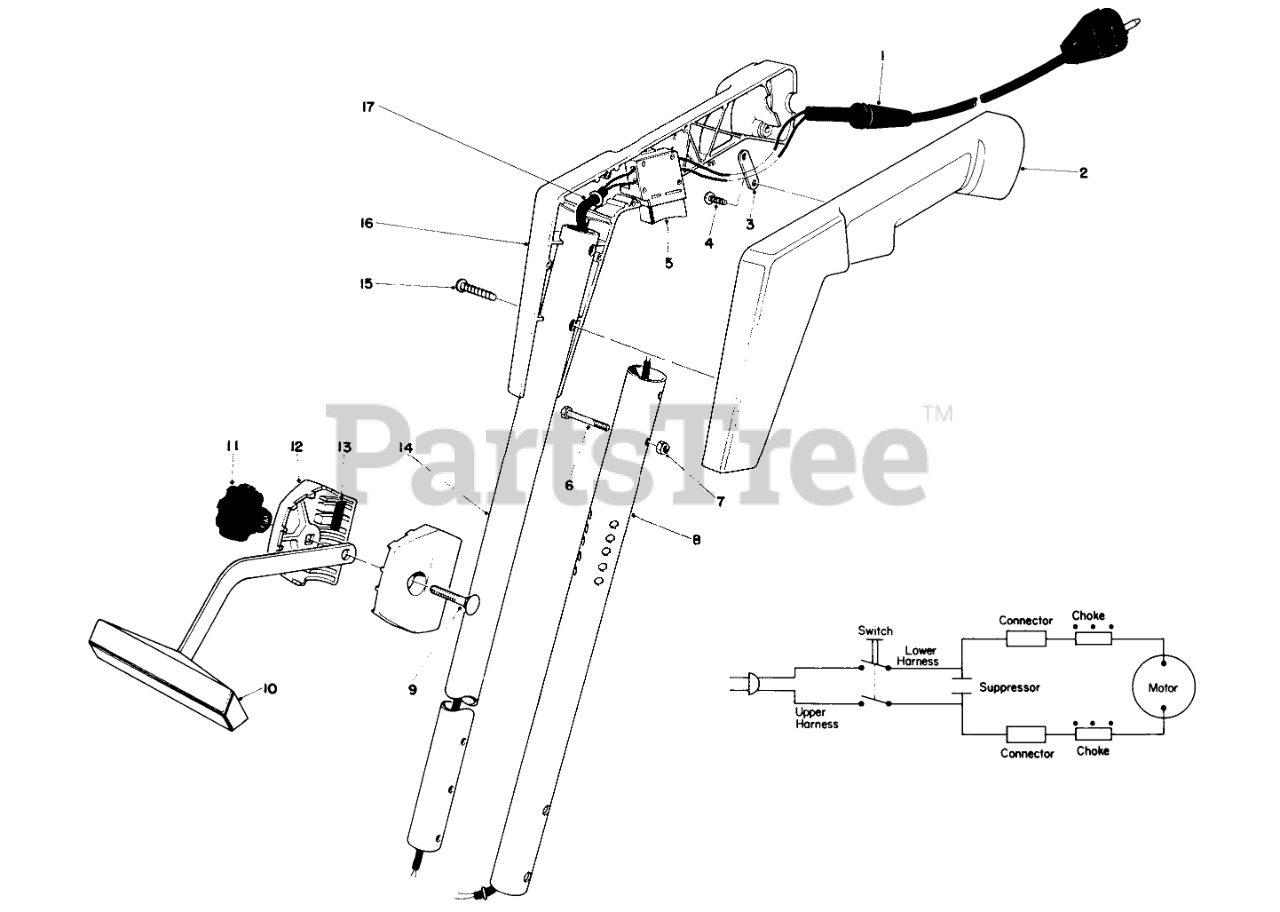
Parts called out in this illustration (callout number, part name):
1	Power Cord
2	Left Hand Grip
3	Clamp
4	SCREW-PPH
5	Switch
6	Screw
7	NUT-LOCK, NI
8	Lower Tubing
9	BOLT-CARR
10	Tee Handle
12	T-HANDLE BRKT(RED)
13	RUBBER INSERT
14	Upper Tubing
16	Right Hand Grip
17	Suppressor
